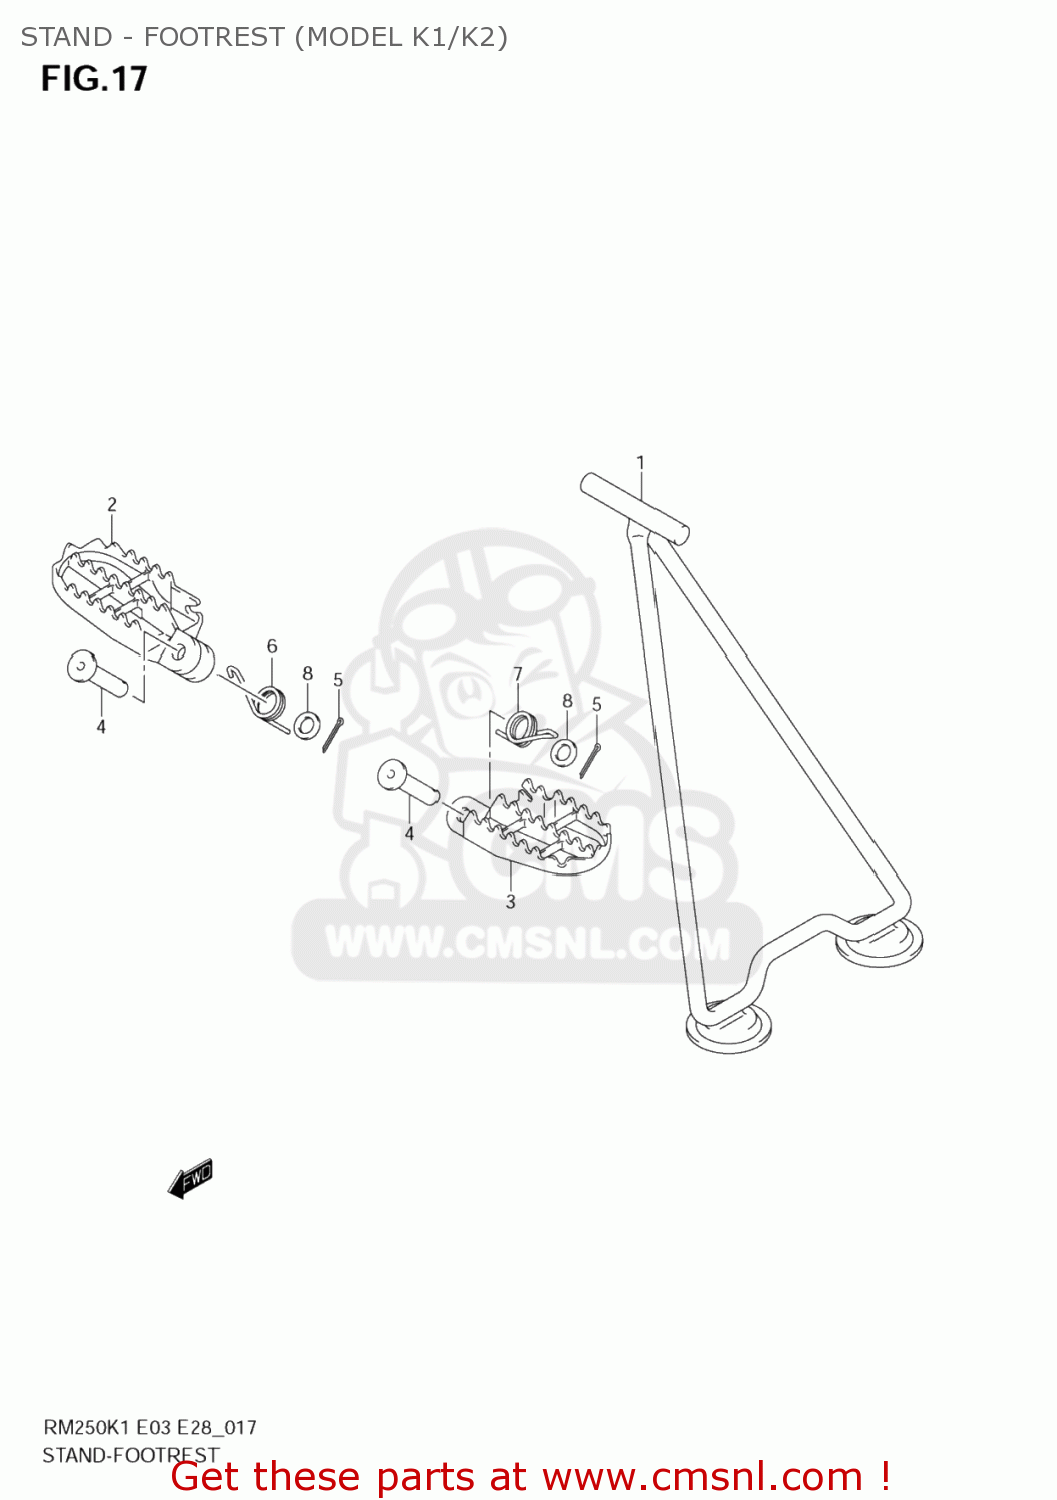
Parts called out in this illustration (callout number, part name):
1	STAND
2	FOOTREST,R
3	FOOTREST,L
4	PIN(10X41.5)
5	PIN 25X20
6	SPRING
7	SPRING
8	WASHER
